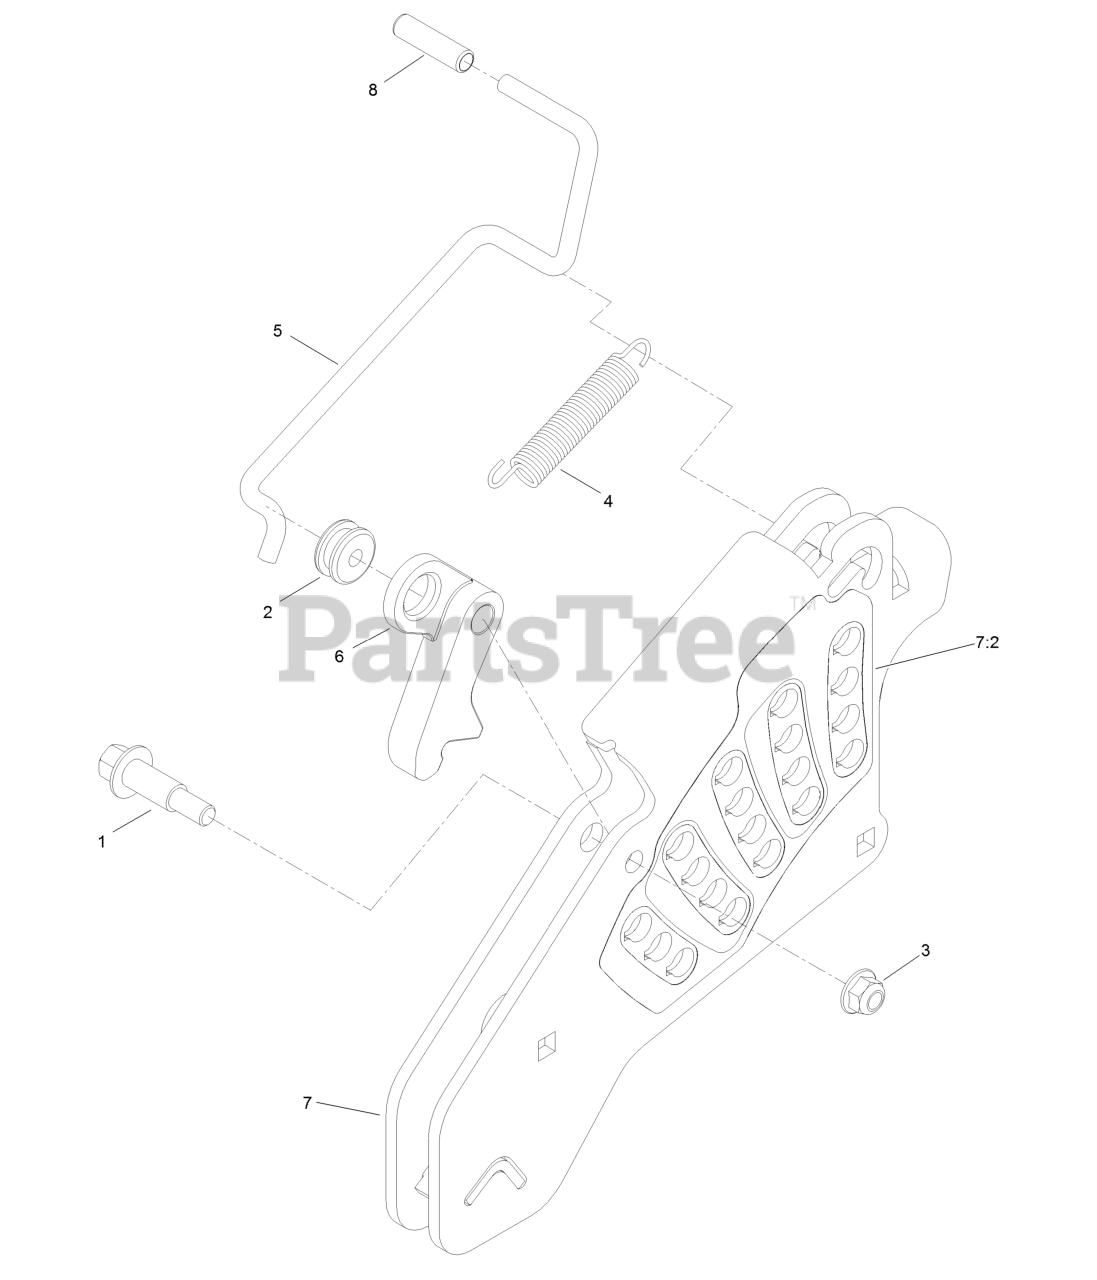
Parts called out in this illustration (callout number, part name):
1	BOLT-SHOULDER
2	GROMMET
3	NUT-HF, NI
4	SPRING-EXTENSION
5	ROD-LOCK, TRANSPORT
6	PAWL-TRANSPORT, HOC
7	HOC PLATE ASM
7:2	DECAL-HOC
8	GRIP-LEVER
